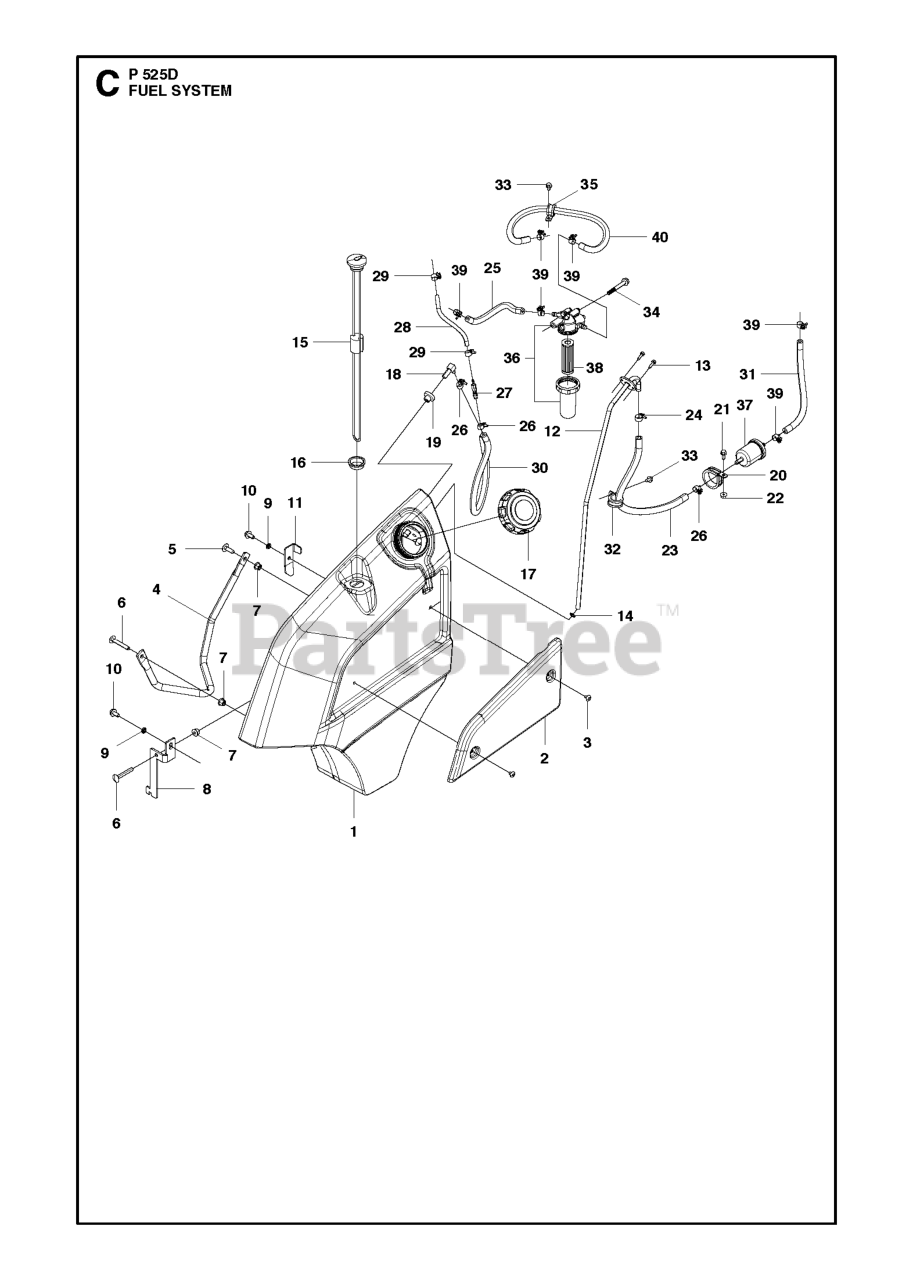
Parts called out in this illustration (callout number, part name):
7	NUT FLANGE
9	WASHER LOCK 8.7X13.5X2.5 ZN FL
17	TANK CAP - DIESEL
19	RUBBER GROMMET
21	SCREW
22	NUT FLANGE
24	HOSE CLAMP FUEL HOSE
26	RP HOSE CLAMP FUEL HOSE
29	HOSE CLAMP FUEL HOSE
32	HOSE CLAMP
35	HOSE CLAMP
39	HOSE CLAMP FUEL
